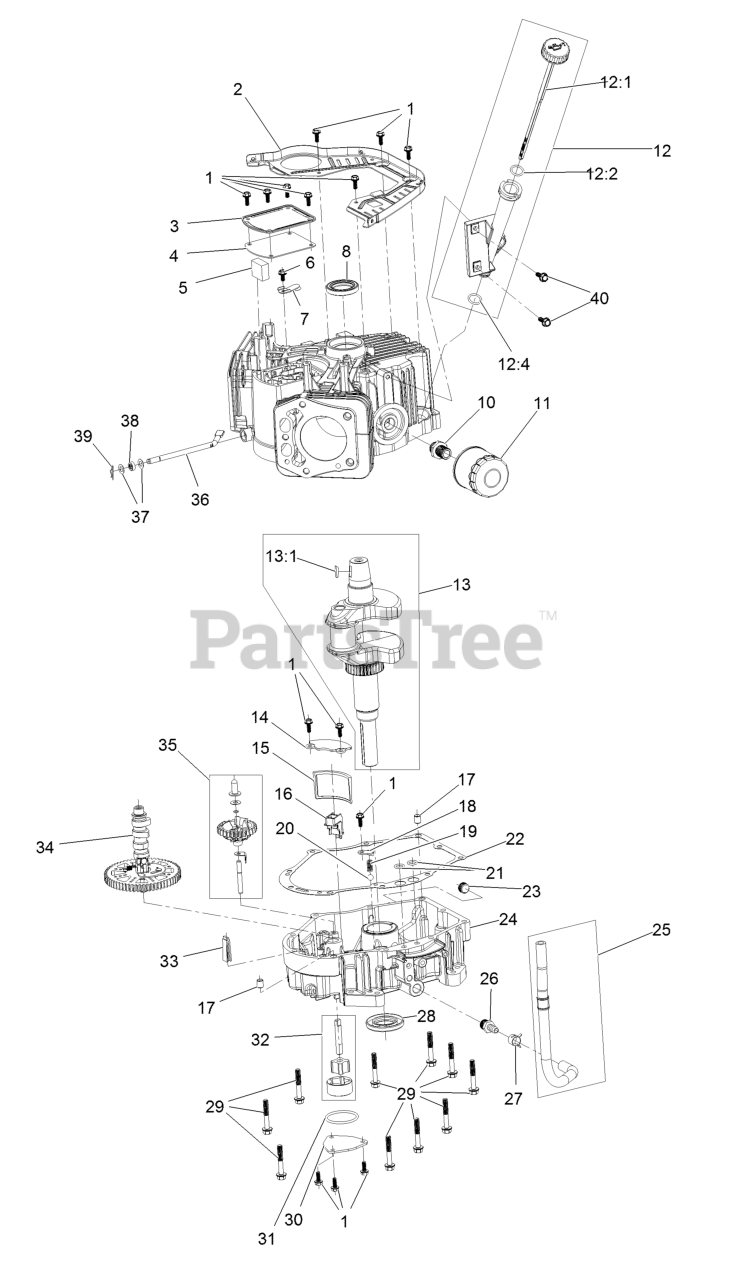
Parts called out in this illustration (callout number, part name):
1	Screw-HHF
3	Cover-Breather
4	Gasket-Breather
5	Filter-Breather
6	Screw-HHF
7	Valve-Breather
8	Seal-Oil
10	Adaptor-Filter, Oil
11	Filter-Oil
12	Oil Tube ASM
12:1	Dipstick
13	Crankshaft
13:1	Key-Woodruff
14	Cover-Screen, Oil
15	Screen-Oil
16	Retainer-Screen
17	Pin-Dowel
18	Plate-Retainer
20	Valve-Ball
22	Gasket-Cover, Crankcase
23	Plug-Drain
24	Cover-Crankcase
25	Oil Drain Hose ASM
26	Fitting-Hose
27	Clamp-Hose
29	Screw-HHF
30	Cover-Oil Pump
32	Oil Pump ASM
33	Deflector-Oil, Rubber
34	Camshaft
35	Governor ASM
36	Shaft-Governor
37	Washer-Plain
38	Seal-Oil
39	Pin-Hair
40	Screw-HHF
